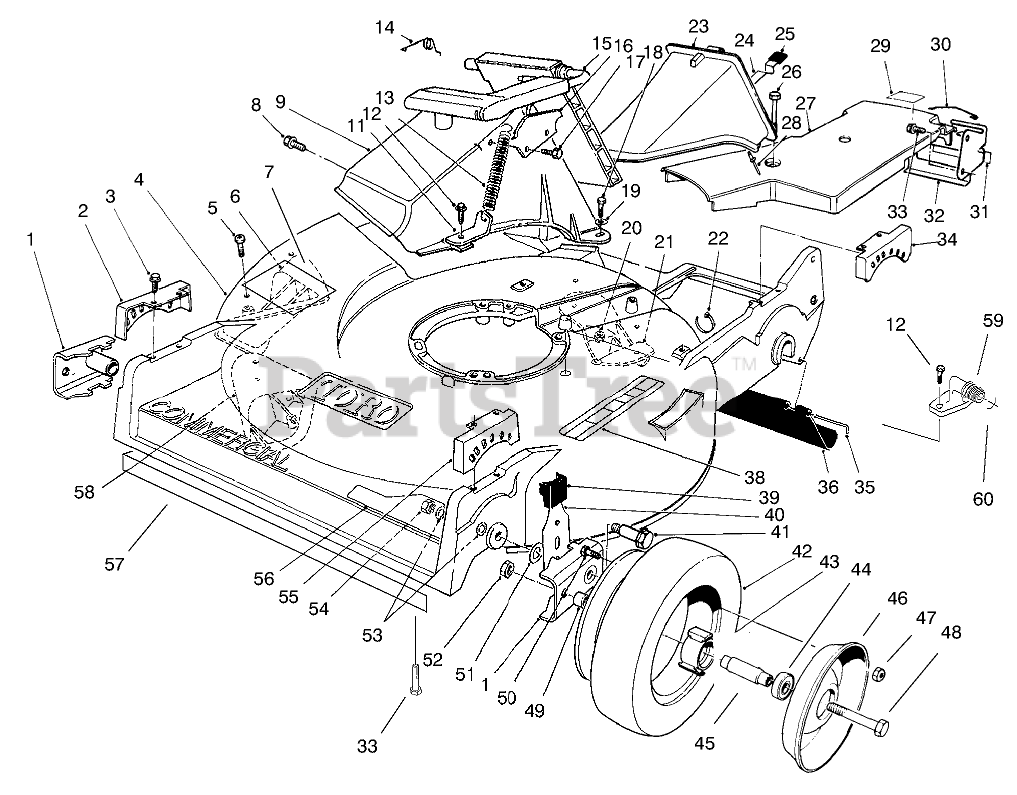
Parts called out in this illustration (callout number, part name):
1	ARM-PIVOT, FRONT
2	QUADRANT-FRONT, RH
3	SCREW-HWHTF
4	Housing-Commercial (Incl. Ref. #5-7, 12, 21, 33, 38, & 57-60)
5	SCREW-PPH
6	KICKER-RH
7	DECAL-DANGER
8	SCREW AND WASHER ASM
9	TUNNEL-DISCHARGE
11	BRACKET-SPRING
12	SCREW-HWH
13	SPRING-DOOR
14	RETAINER-DOOR
15	DOOR ASSEMBLY
16	DOOR LATCH PLATE
17	SCREW-PLASTITE
18	SCREW-HH
19	WASHER-FLAT
20	NUT-LOCK, NI
21	KICKER-REAR
22	TIE-CABLE
23	Plug Assembly (Incl. Ref. #24, 25, & 28)
24	LATCH-PLUG, DISCHARGE
25	GRIP-LATCH
26	SCREW-HHFTF
27	COVER-BELT
28	RIVET-HEAD, FLAT
29	DECAL-GREASE
30	RETAINER-CABLE
31	DECAL-POSITION, GEAR
32	BRACKET-ADJUSTMENT, TRACTION
33	SCREW-HWHTF
34	QUADRANT-REAR, LH
35	ROD-SHIELD
36	SHIELD-TRAILING
38	DECAL-DANGER
39	KNOB-ARM
40	FRONT SPRING ARM ASM
41	BOLT-WHEEL
43	HUB-BEARING
44	BEARING-WHEEL
45	SPACER-BEARING
46	Wheel-Half
47	NUT-LOCK, NI
48	SCREW-HH
49	SPACER-WHEEL
50	SCREW-HH
51	WASHER-THRUST
52	NUT-LOCK, CONE
53	WASHER
54	NUT-LOCK
55	QUADRANT-FRONT, LH
56	DECAL - DECK
57	Shield-front
58	KICKER-FRONT
59	FITTING-WASHOUT
60	O-RING
